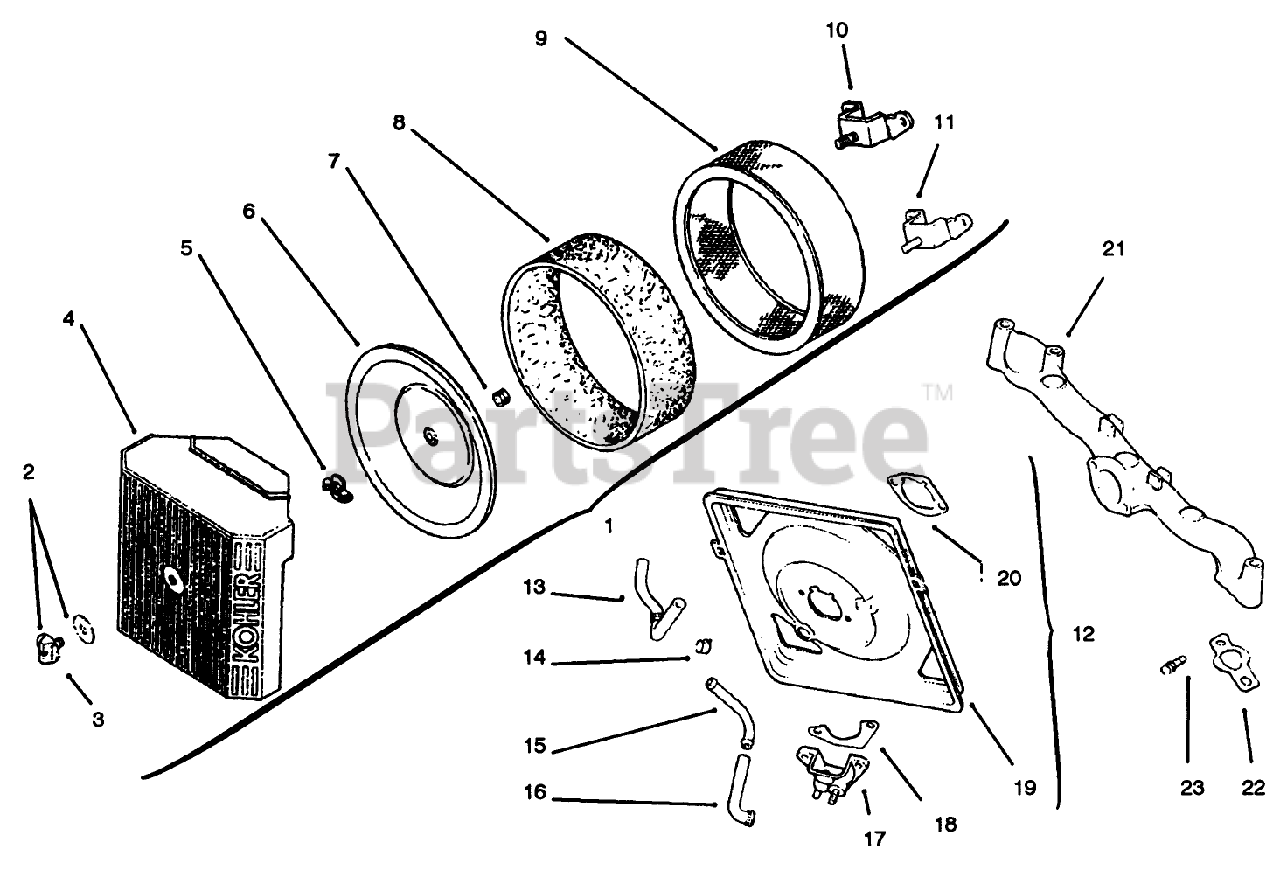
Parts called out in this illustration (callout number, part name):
1	Kit-Air Cleaner Cover
2	Kit-Knob w/Gasket
3	Knob-Cover
4	Cover-Air Cleaner
5	Nut-Wing
6	Cover-Inner Air Cleaner
7	Seal-Air Intake (Only On: 72103)
8	Element-Precleaner
9	Element-Air Cleaner
10	Bracket-Air Cleaner
11	Bracket-Air Cleaner
12	Kit-Air Cleaner Base
13	Hose-Breather
14	Clamp
15	Fitting
16	Hose-Breather
17	Cup-Fuel Spitback
18	Gasket-Fuel Spitback Cup (Only On: 72103, 72083)
19	Base-Air Cleaner
20	Gasket-A/C Base (Only On: 72103, 72083)
21	Manifold-Intake (Only On: 72103)
22	Gasket-Intake Manifold
